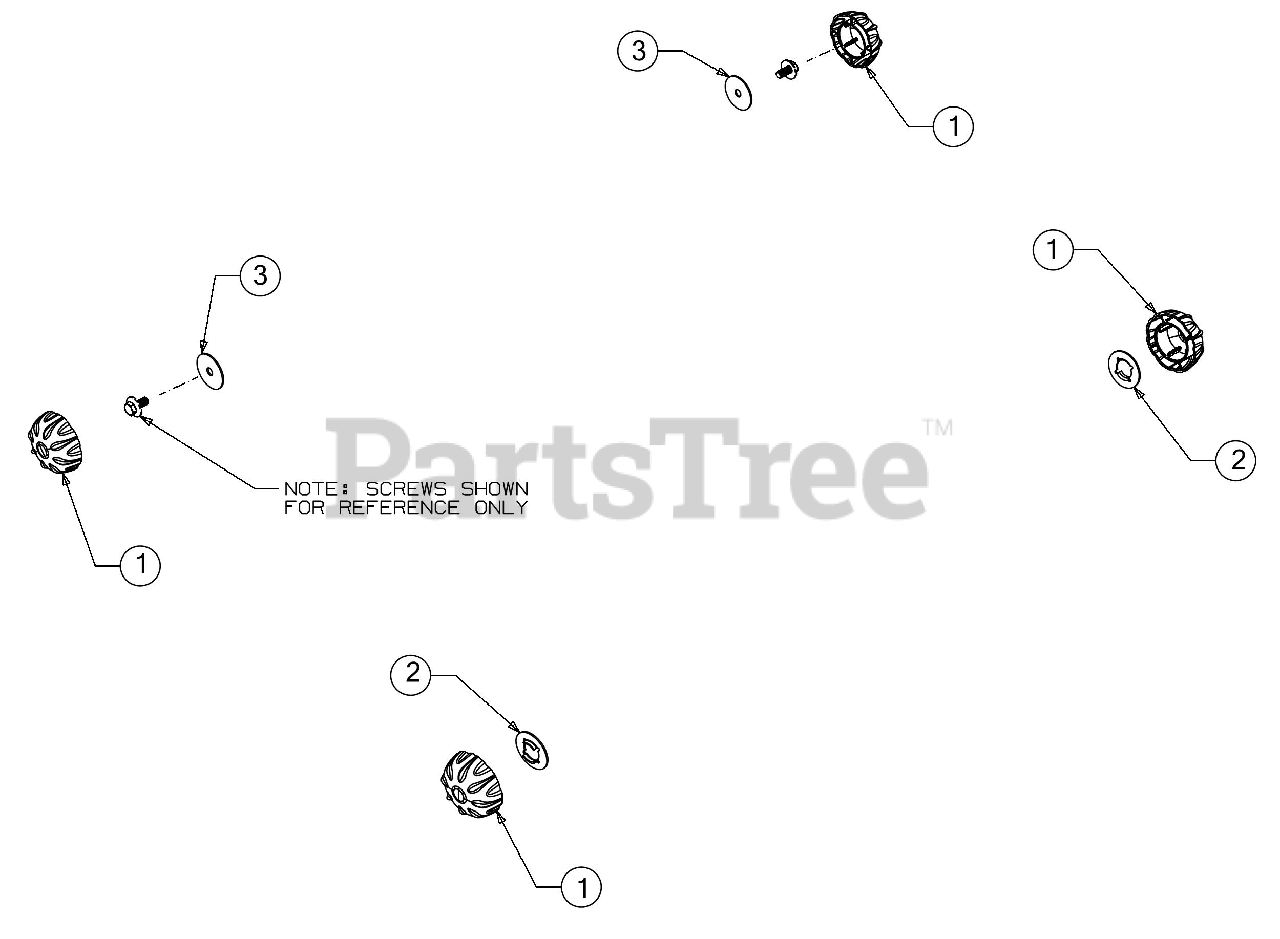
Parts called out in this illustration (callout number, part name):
1	HUB CAP
2	FLAT WASHER .781 ID x1.590 OD
3	FLAT WASHER .350X1.59X.062
